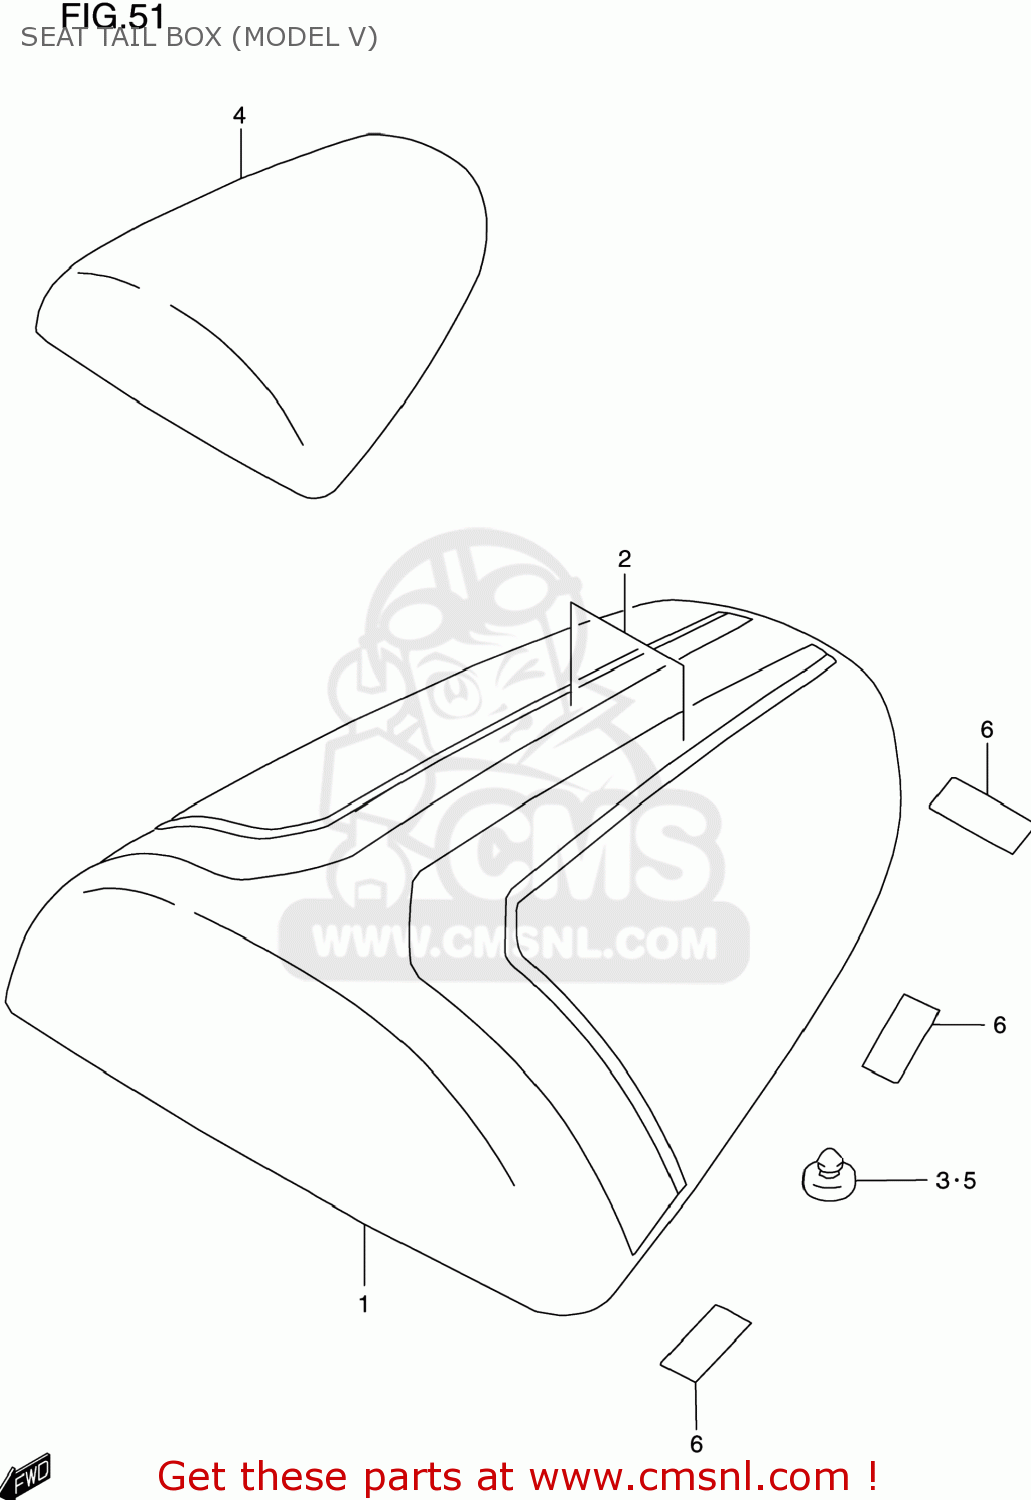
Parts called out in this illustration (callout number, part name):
1	BOX ASSY,SEAT TAIL(WHITE)
2	TAPE SET,BOX SEAT TAIL
3	CUSHION(11.5X22X20)
4	BOX,SEAT TAIL(GRAY)
5	CUSHION(11.5X22X20)
6	PROTECTOR SET,SEAT TAIL BOX
